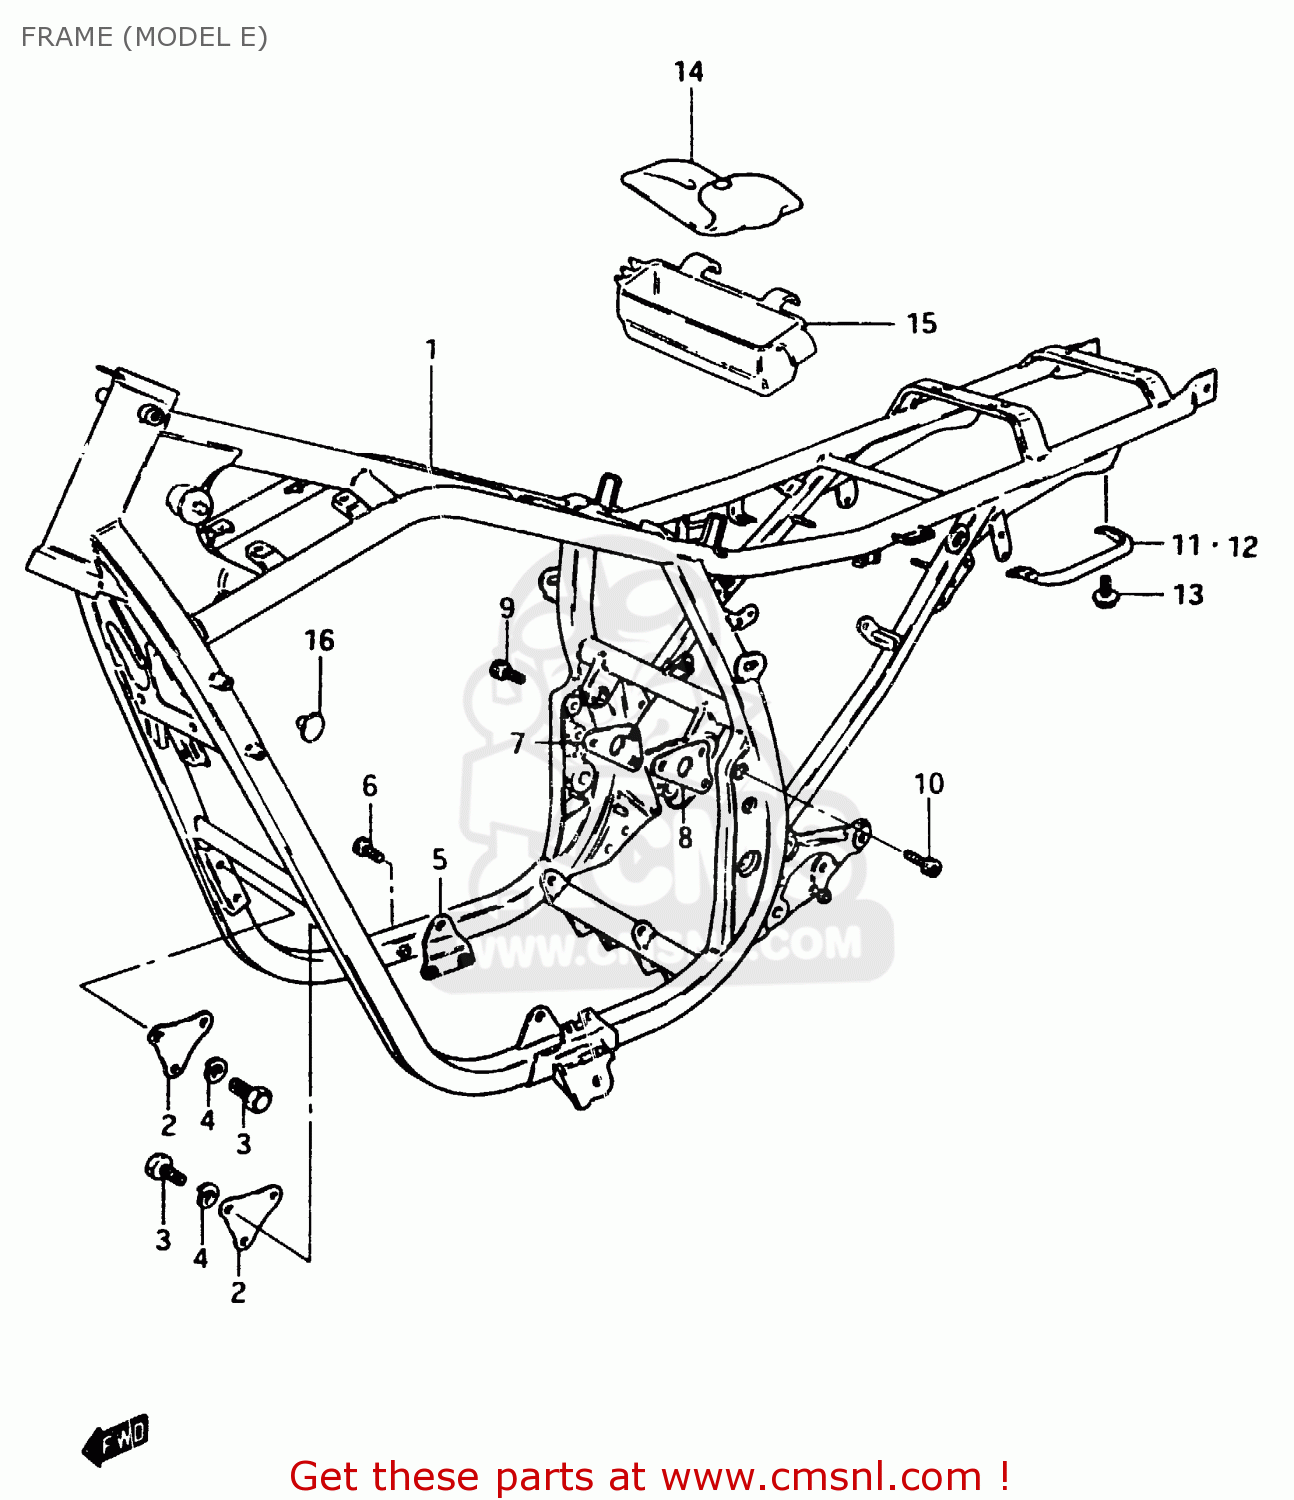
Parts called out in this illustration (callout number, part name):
1	FRAME (SILVER)
2	PLATE,ENGINE MOUNTING NO
3	BOLT
4	LOCK WASHER
5	PLATE,ENGINE MOUNTING NO
6	BOLT
7	PLATE,ENGINE MOUNTING NO
8	PLATE,ENGINE MOUNTING NO
9	BOLT
10	BOLT
11	GRIP,FRAME HANDLE,RIGHT
12	GRIP,FRAME HANDLE,LEFT
13	BOLT, LOWER
14	TOOL SET
15	HOLDER,TOOL
16	PLUG(OD:12)
